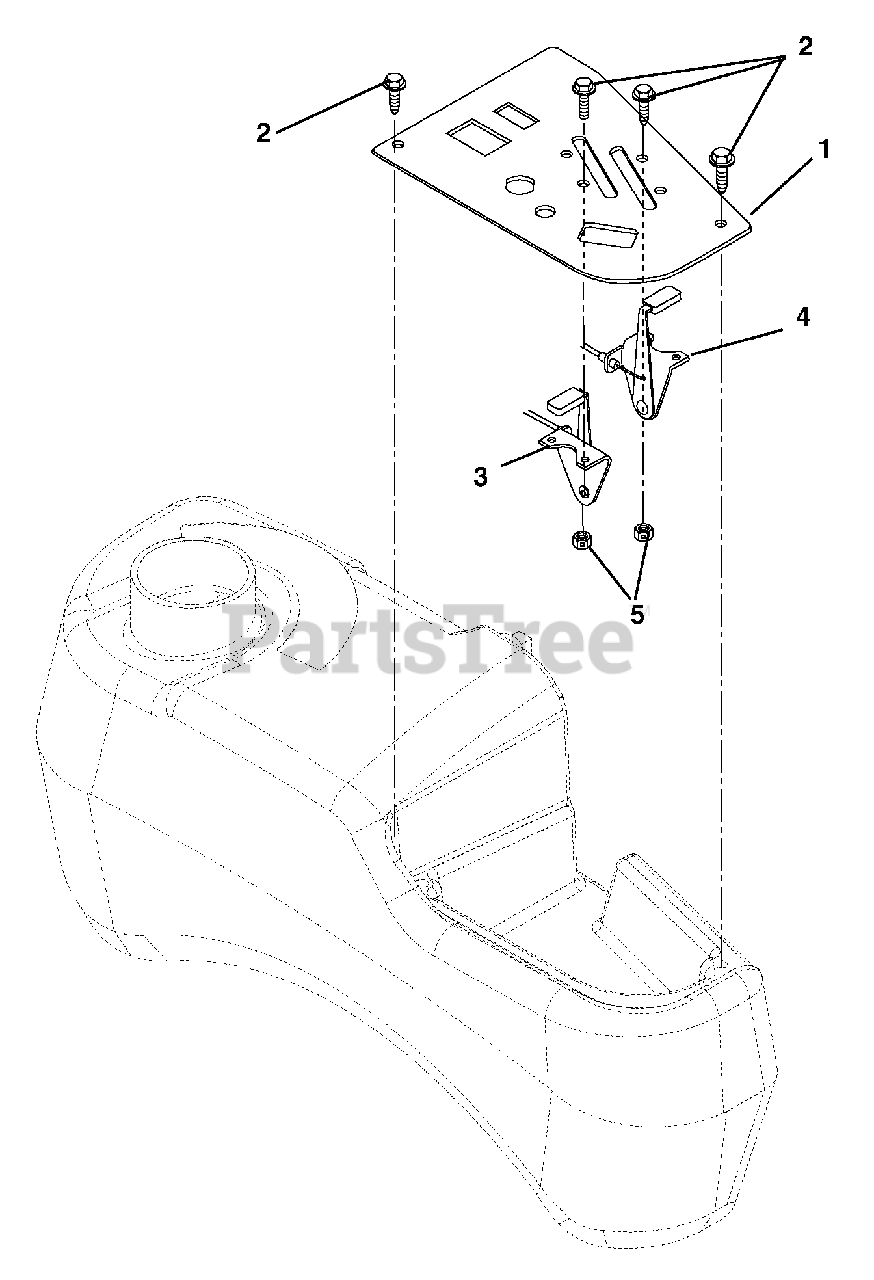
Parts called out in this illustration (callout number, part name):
1	Panel, Control
2	Screw, Machine 10-24 x .50 Hex Washer Head
3	Cable, Throttle
4	Cable, Choke, Kohler (054, 055)
4	Cable, Choke, Kawasaki (042, 043, 044, 051, 310, 311)
5	Nut, Locking Nylon 10-24 With Insert
